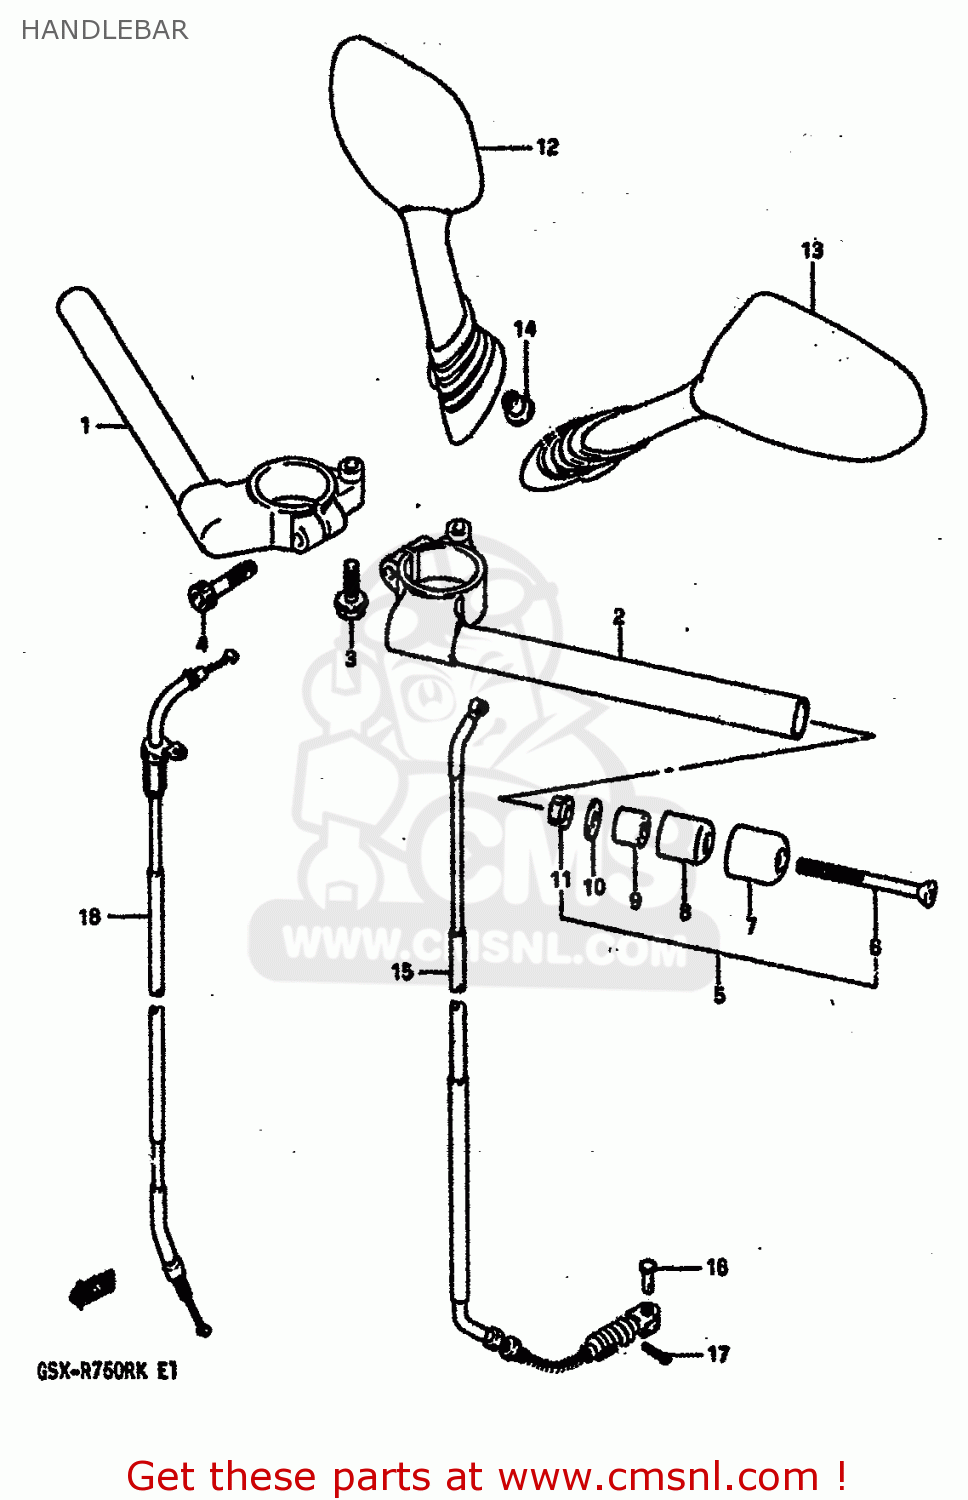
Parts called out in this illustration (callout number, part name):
1	HANDLEBAR,RH
2	HANDLEBAR,LH
3	BOLT 6X25
4	BOLT 8X35
5	BALANCER SET
6	SCREW
7	CAP,BALANCER
8	BALANCER,HANDLEBAR
9	EXPANDER,HANDLE BALANCER
10	SPACER,BALANCER
11	NUT
12	MIRROR ASSY,RR VIEW,R
13	MIRROR ASSY,RR VIEW,L
14	NUT,RR VIEW MIRROR
15	CABLE ASSY,CLUTCH
16	PIN(L:15)
17	PIN
18	CABLE ASSEMBLY,THROTTLE
